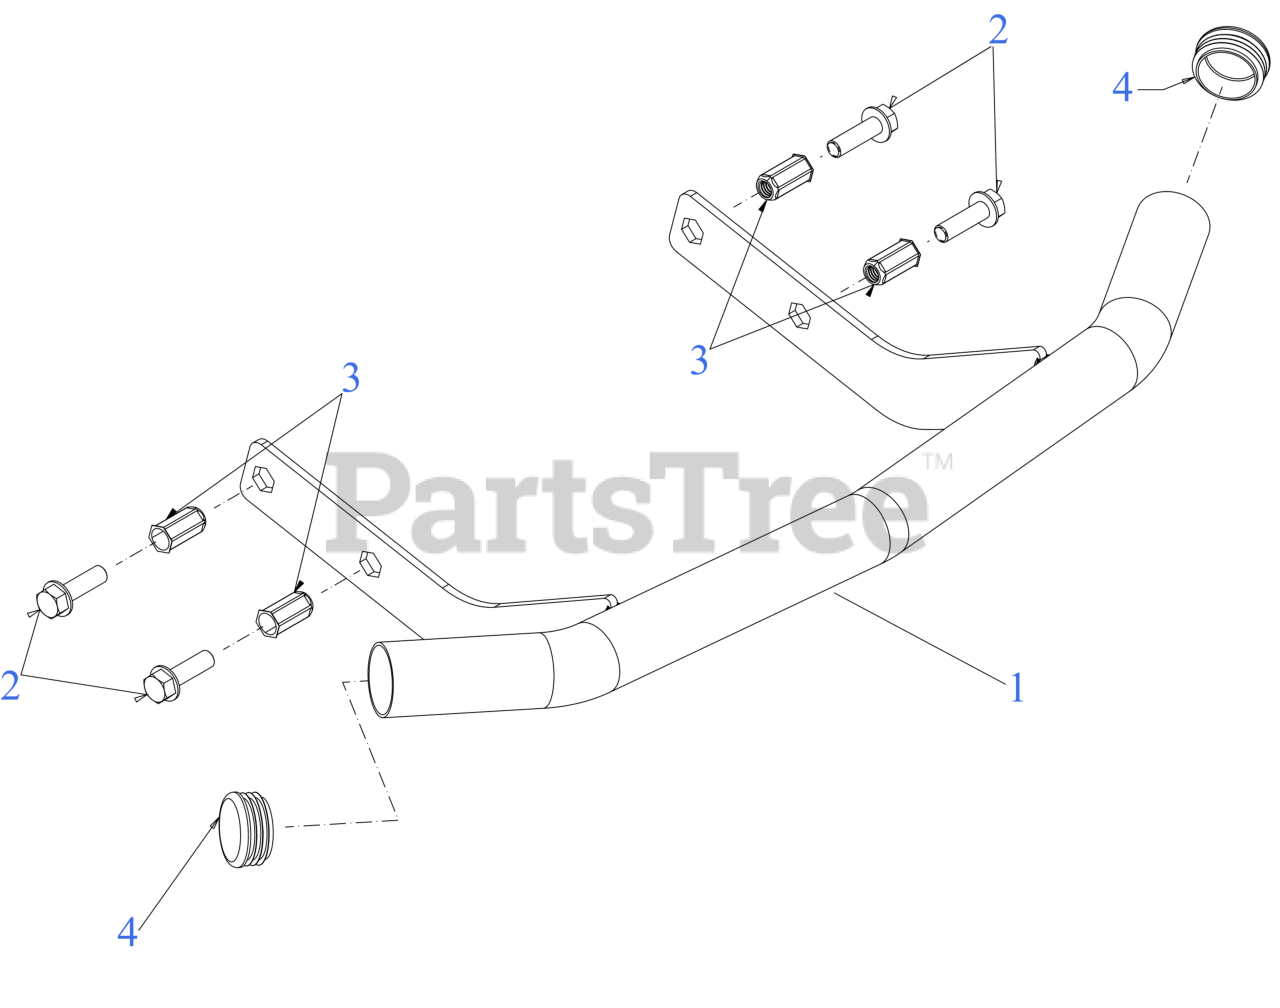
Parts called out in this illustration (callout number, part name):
1	BUMPER ASSEMBLY (YELLOW)
2	SCREW 3/8-16 x 1.25 GR5
3	NUT RIVET 3/8-16
4	BUMPER CAP
